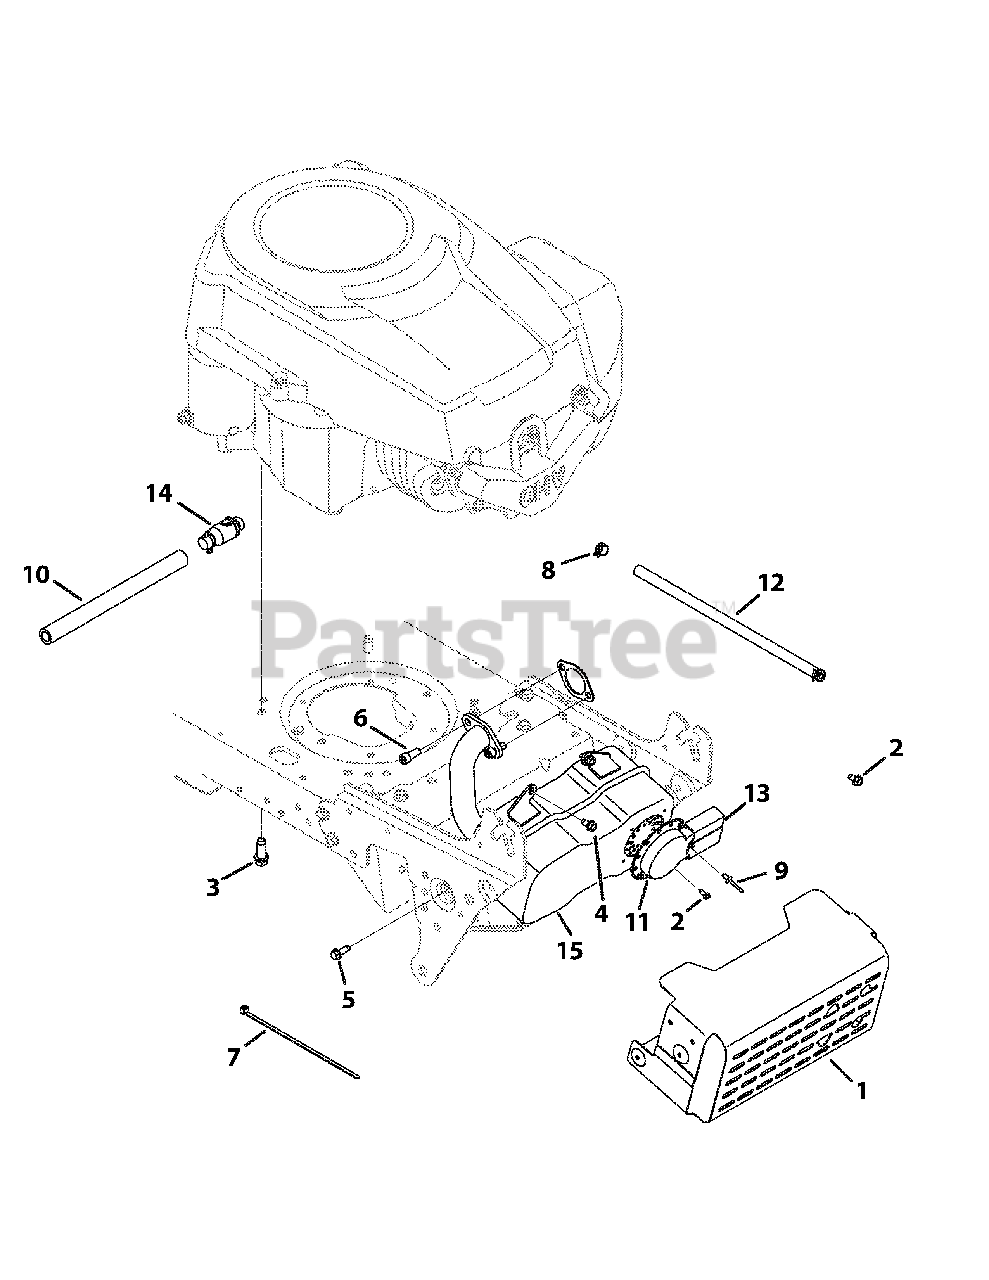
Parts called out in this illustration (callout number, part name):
1	Muffler Shield Assembly with Weld
2	Screw, 8-18 x .500
3	Screw, 3/8-16 x 1.0
4	Screw, 1/4-20 x .500
5	Screw, 1/4-20 x .750
6	Socket Screw, 5/16-18 x .750
7	Cable Tie
8	Clamp Hose, .490 diameter
9	Rivet, .188 x .300
10	Oil Drain, Extension Hose
11	Muffler Deflector
12	Fuel Hose, Low Permeation
13	Muffler Deflector Long
15	Muffler
